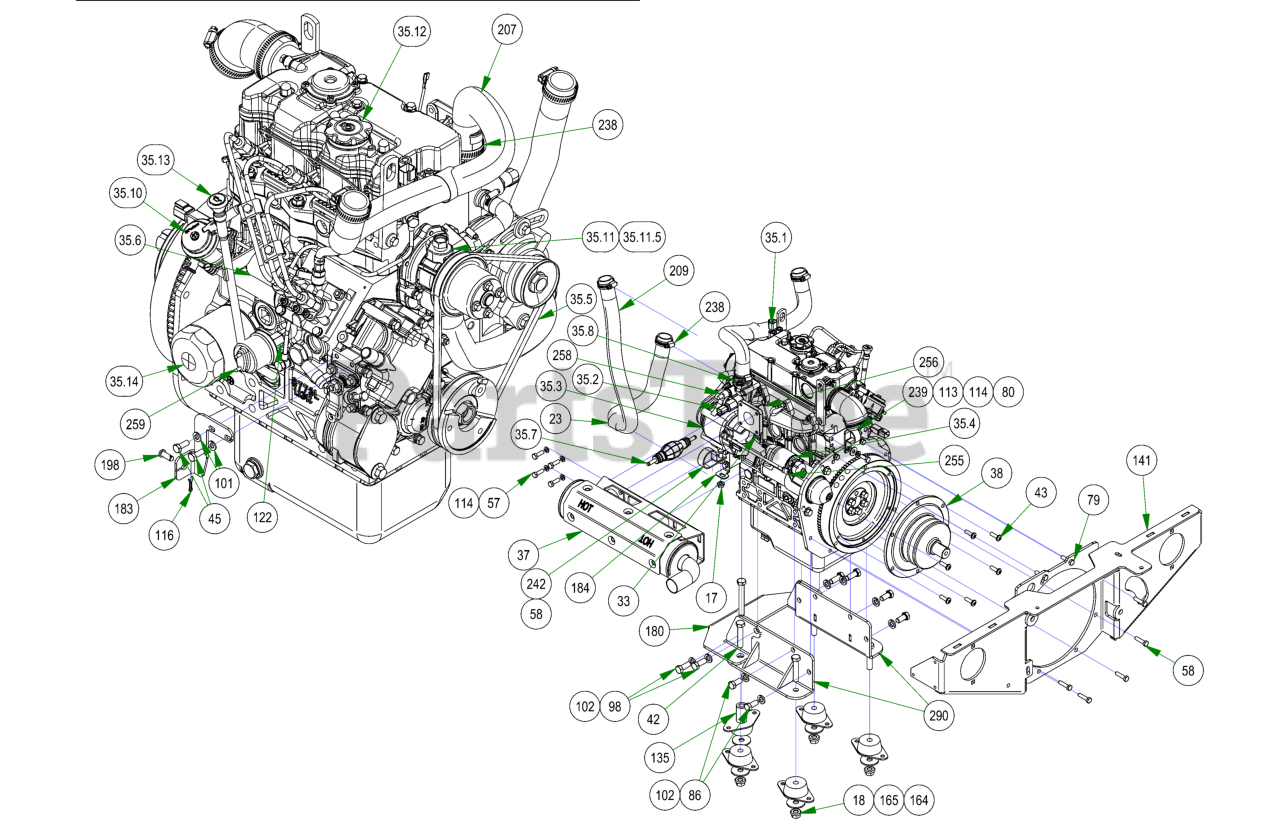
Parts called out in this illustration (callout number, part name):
23	2019 Plastic Mesh Hose Loom
33	Diesel Muffler Gasket
35	24.7HP Perkins Engine, 403J-11
35.1	OIL PRESSURE SWITCH
35.2	COOLANT TEMPERATURE SWITCH
35.3	ALTERNATOR
35.5	ALTERNATOR BELT
35.6	FUEL SHUTOFF SOLENOID
35.7	FUEL PRIMING BULB PUMP
35.8	THERMOSTAT GASKET
35.10	FUEL LIFT PUMP
35.11	WATER PUMP WITH GASKET
35.11.5	THERMOSTAT
35.12	OIL FILLER CAP
35.13	OIL LEVEL DIPSTICK
35.14	OIL FILTER
37	2019 Renegade 1100cc Diesel Muffler
38	2019 Diesel Stub Shaft Double V
42	1/2-13 X 2-1/2 HEX CAP SCREW GR 5 ZINC
43	5/16-18 X 1 BUTTON TORX CAP SCREW ZINC
44	5/16-18 X 2-1/4 HEX CAP SCREW (GR.5) ZINC
57	M8-1.25 X 25MM DIN 933 HEX TAP BOLT (CL 10.9) ZINC
74	1/2-13 X 4 HEX CAP SCREW (GR.8) ZINC YELLOW
79	M8-1.25 X 30MM DIN 933 HEX TAP BOLT (CL 10.9) ZINC
80	M8-1.25 X 20MM DIN 933 HEX TAP BOLT (CL 8.8) ZINC
86	M12-1.25 X 25MM DIN 961 HEX TAP BOLT (CL 8.8) ZINC
98	M12-1.25 X 30MM DIN 961 HEX TAP BOLT (CL 8.8) ZINC
102	1/2 SPLIT LOCKWASHER (GR.8) ZINC/YELLOW
113	5/16 USS FLAT WASHER (7/8 OD) ZINC
114	5/16 SPLIT LOCKWASHER ZINC
116	3/32 X 1/2 COTTER PIN ZINC
122	8mm x 1/8 mpt Adaptor
128	.380 ID X .625 OD X 1.500 LGTH 2019 OUTLAW BRAKE HANDLE SPACER ZINC
131	ACS Spacer 3/4x3/8x1/4
135	1 3/4" Pulley Spacer
165	.520 ID X 1.750 OD X .120 THICK FLAT WASHER ZINC
180	2022 Renegade Diesel Front Engine Mount
183	Throttle Bracket
184	Diesel Radiator Hose Clamp Bracket
198	1/4 X 5/8 CLEVIS PIN PLAIN
207	2019 Diesel Radiator Hose Upper
208	2019 Diesel Air intake Hose
209	2019 Diesel Radiator Hose Lower
238	1 1/8" Hose Clamp
239	Diesel Hydraulic Hose Clamp
255	Red Battery Cable Alternator to Starter Cable
256	2022 DIESEL JUMPER WIRE, WHITE, 14AWG
258	Coolant Temperature Sender
259	Oil Pressure Guage with Sender
283	Patent Decal (ROGUE/RENEGADE)
